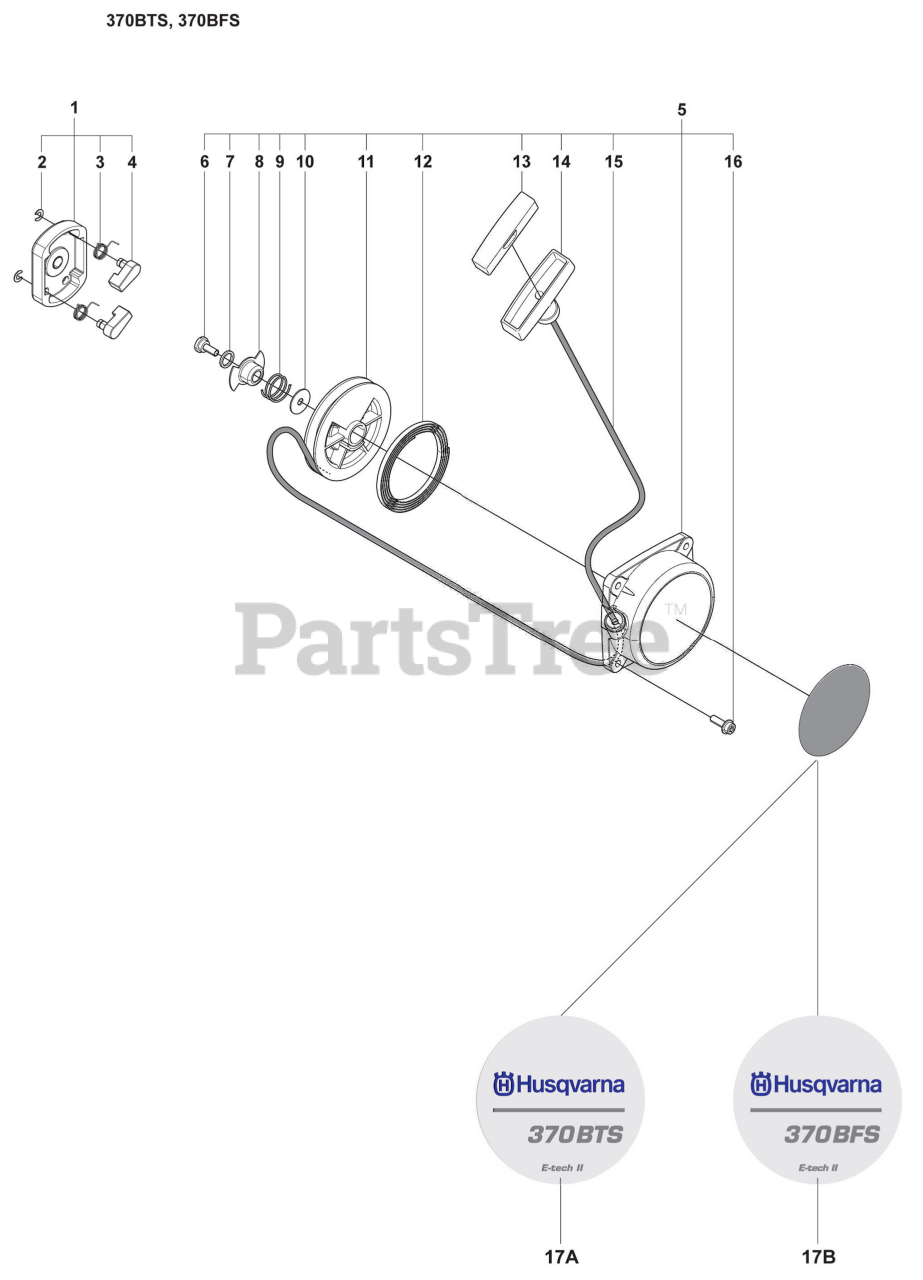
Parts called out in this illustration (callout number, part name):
1	Pulley Assembly
2	E-Ring
5	Recoil Assembly
6	Screw
7	Washer
8	Friction Plate
9	Friction Spring
10	Washer
11	Reel
12	Spring
13	Cover
14	Knob
16	Bolt
17A	LABEL
17B	HHFS 1/2-13 X 4.0 GD8 ZD
